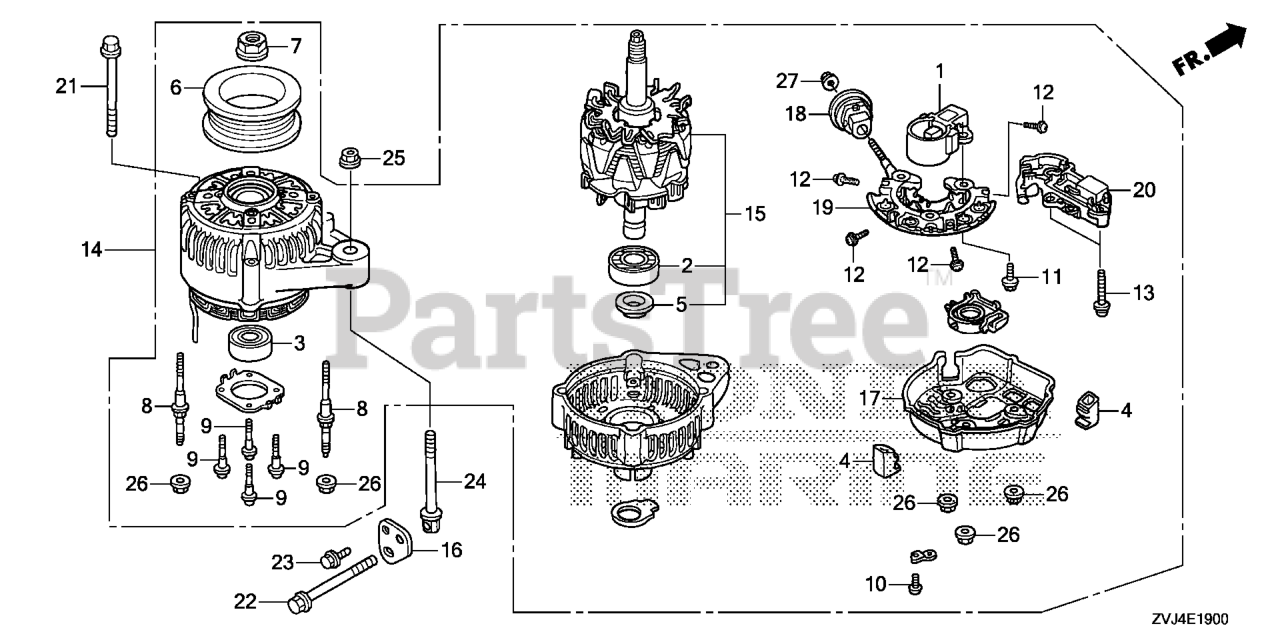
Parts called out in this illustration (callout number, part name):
1	HOLDER ASSY., BRUSH
2	BEARING, RR. GENERATOR
3	BEARING, FR. GENERATOR
4	BUSH, INSULATION
5	COVER, BEARING
7	NUT, PULLEY LOCK
8	BOLT, STUD (6X68)
11	SCREW-WASHER
12	SCREW, WAVE WASHER
13	SCREW, WAVE WASHER
14	ALTERNATOR ASSY.
15	ROTOR ASSY.
16	STAY, ALTERNATOR
17	END COVER, RR.
18	BUSH, INSULATION
19	RECTIFIER ASSY.
20	REGULATOR ASSY.
21	BOLT, FLANGE (10X90)
22	BOLT, SPECIAL ADJUSTER
22	BOLT, SPL ADJ
23	BOLT, FLANGE (6X16)
24	BOLT, TENSIONER
25	NUT, FLANGE (8MM)
26	NUT-WASHER (5MM)
27	NUT, HEX. (6MM)
